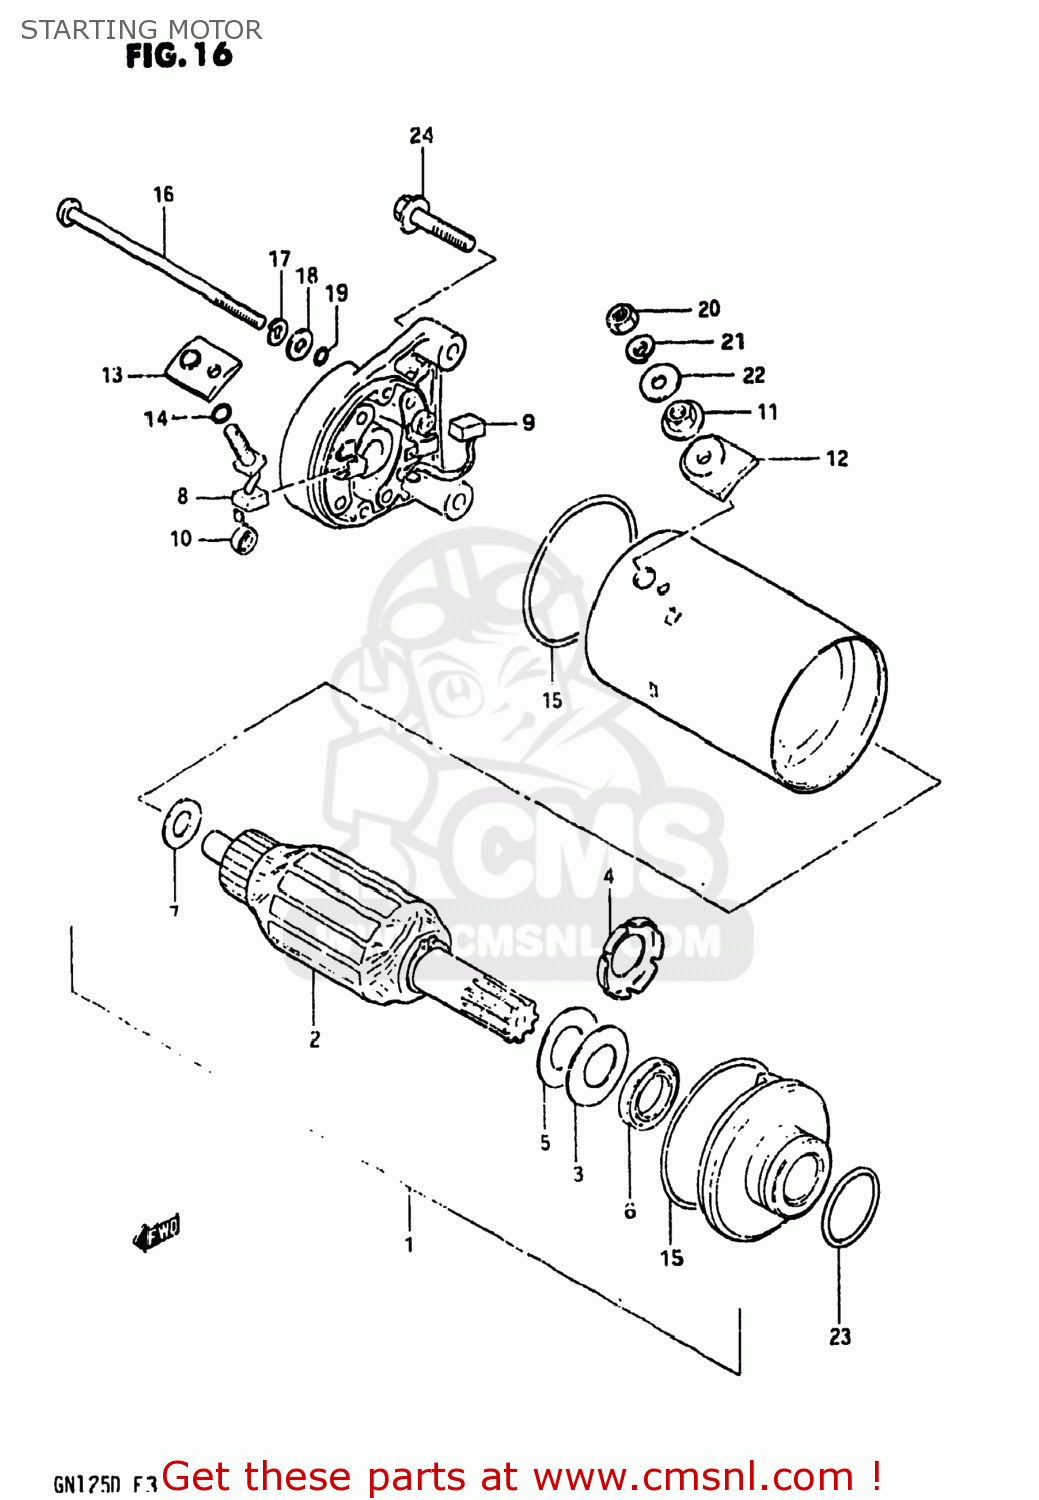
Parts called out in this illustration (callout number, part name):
1	MOTOR ASSEMBLY,STARTING
2	ARMATURE
3	RING,SNAP
4	SHIM,ARMATURE
5	SHIM
6	SEAL,OIL
7	SHIM,ARMATURE
8	BRUSH(+)
9	BRUSH(-)
10	SPRING
11	NUT 6MM
12	BUSH,A
13	BUSH,B
14	O RING
15	O-RING
16	BOLT
17	LOCK WASHER
18	WASHER
19	O RING
20	NUT 6MM
21	LOCK WASHER
22	WASHER (6.7X16X1.8)
23	O RING(D:2,ID:24.5)
24	BOLT (6X30)
